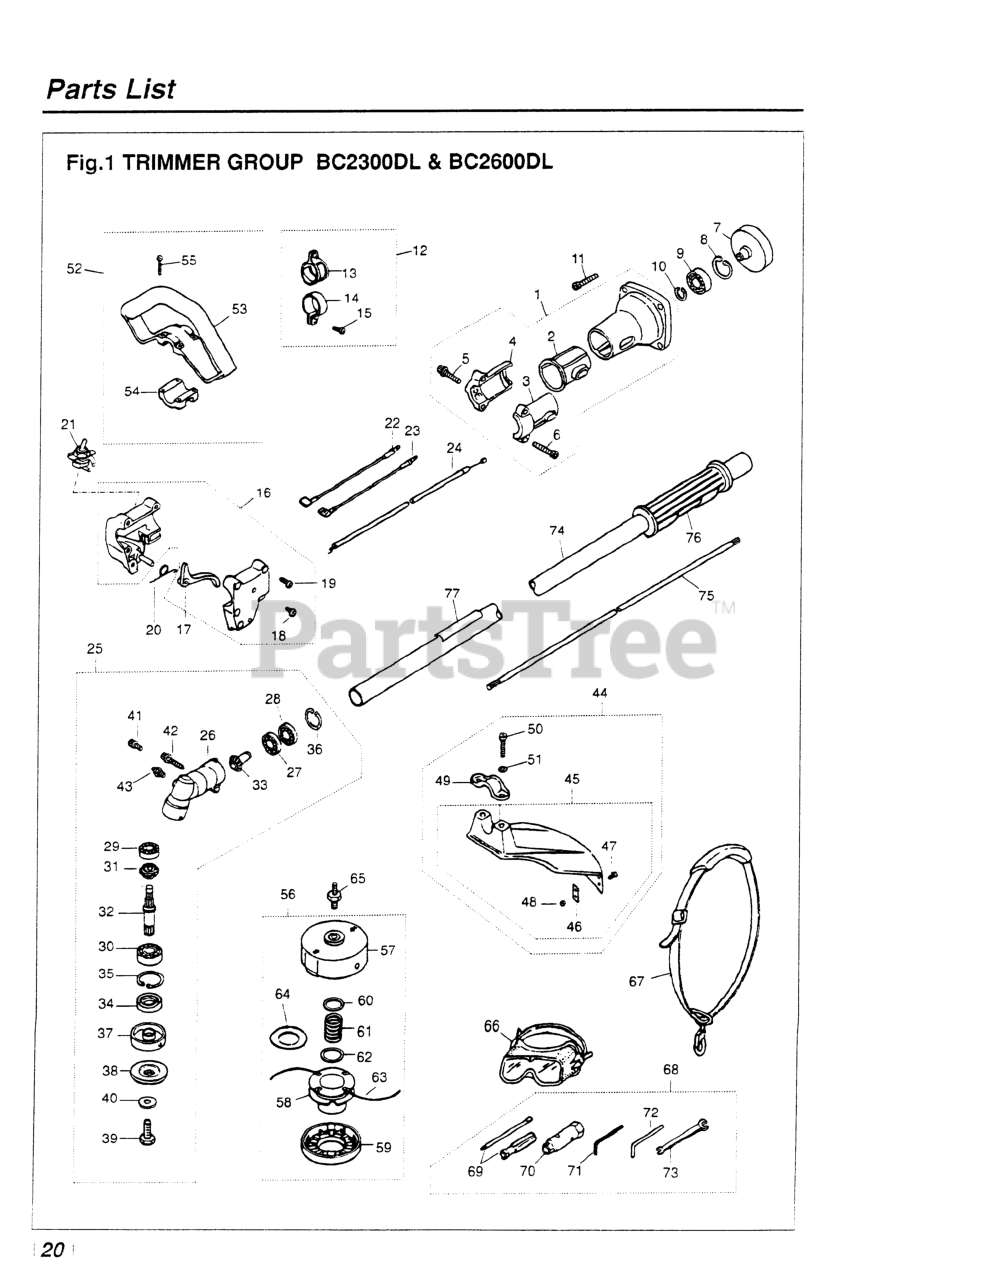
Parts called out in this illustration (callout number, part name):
2	CUSHION
3	BRACKET (USE -31211)
4	BRACKET (USE -31221)
5	BOLT (USE 3310-31720)
6	BOLT, M5 X 30
8	RING, SNAP, M28 x 1.2
9	BEARING
10	RING, SNAP (RPLS 3130-13270)
11	BOLT, M6 x 20
12	HANGER COMPLETE
13	HANGER
14	CLAMP
15	SCREW, M5 x 25
17	THROTTLE HSG & TRIGGER
18	SET SCREW, ANTI-ROTATION
19	SCREW
20	SPRING, THROTTLE TRIGGER
21	SWITCH, STOP
22	CORD, RED (LEAD WIRE)
23	CORD, BLACK (LEAD WIRE)
24	CABLE COMP (RPLS 6460- )
25	GEARCASE ASSEMBLY
26	GEARCASE
27	BEARING
28	BEARING
29	BEARING
30	BEARING
31	GEAR
33	PINION
34	SEAL, OIL
35	RING, SNAP
36	RING, SNAP
37	HOLDER (A)
38	HOLDER (B)
40	WASHER
41	BOLT, M5 x 12
42	BOLT, M5 X 25
43	FITTING, GREASE
44	GUARD ASSEMBLY
46	BLADE
47	SCREW, M5 x 12
48	NUT
49	CLAMP
50	BOLT, M6 x 1.30
51	WASHER, M6 X 15
52	HANDLE ASSEMBLY
53	HANDLE
54	CLAMP
55	SCREW, M5 x 35
56	4
59	COVER (RPLS -15130)
60	PLATE, LARGE
62	PLATE, SMALL
63	CORD
64	SPACER
65	ARBOR, 8MM
66	GOGGLE
67	SHOULDER STRAP ASSY
68	TOOL SET
69	SCREWDRIVER
71	WRENCH (TOOL)
72	BAR
73	SPANNER, 8 X 10 (RPLS 2540- )
77	LABEL, BC2300/2600DL
